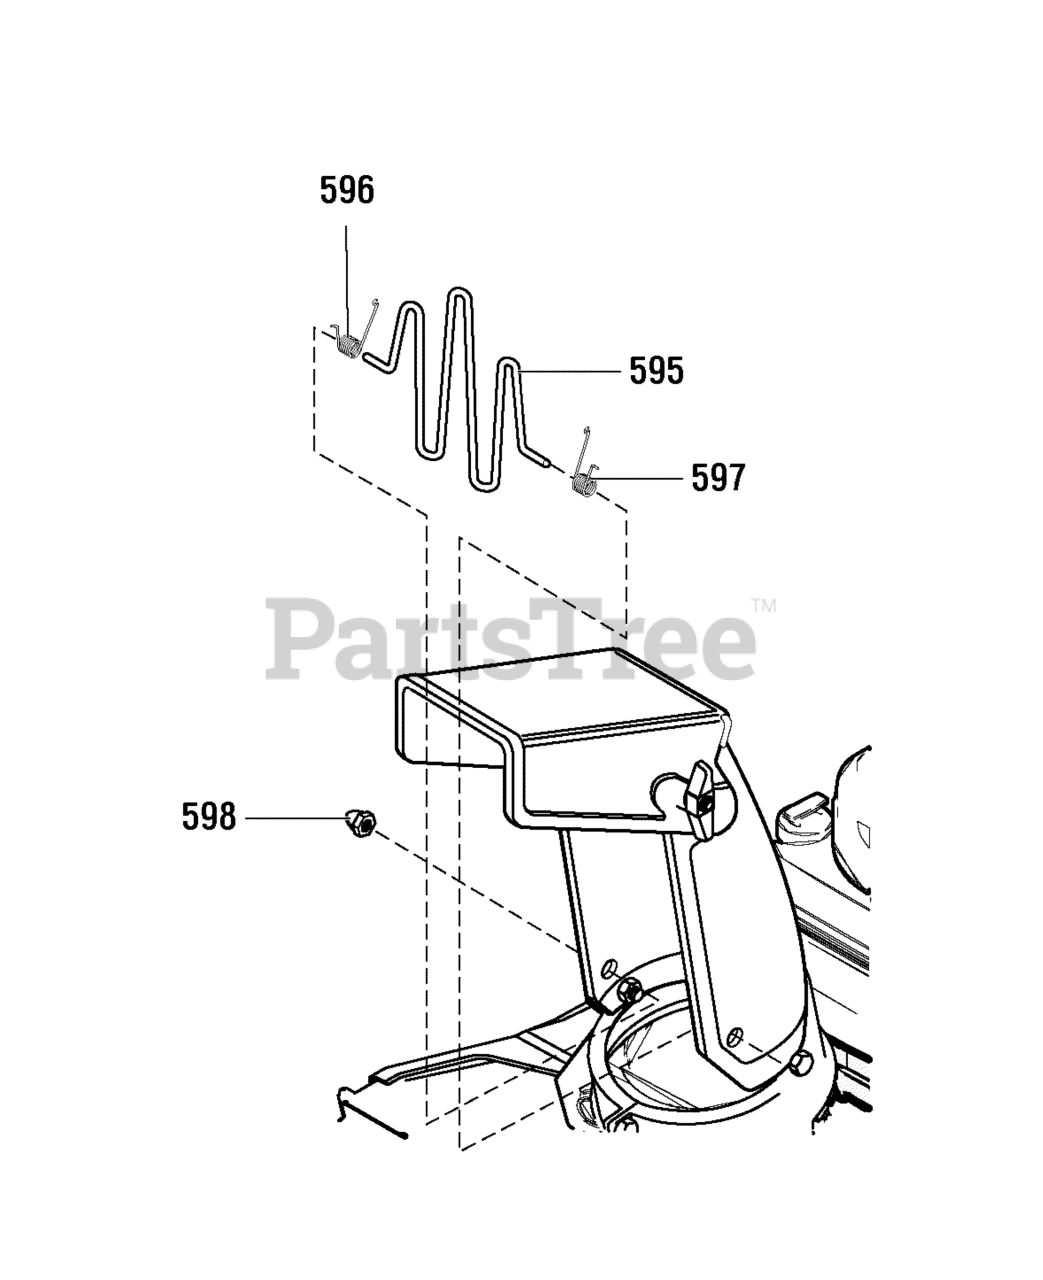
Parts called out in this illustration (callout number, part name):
595	GUARD, WIRE CHUTE
596	SPRING, TORSION
597	SPRING, TORSION
598	NUT, ACORN
